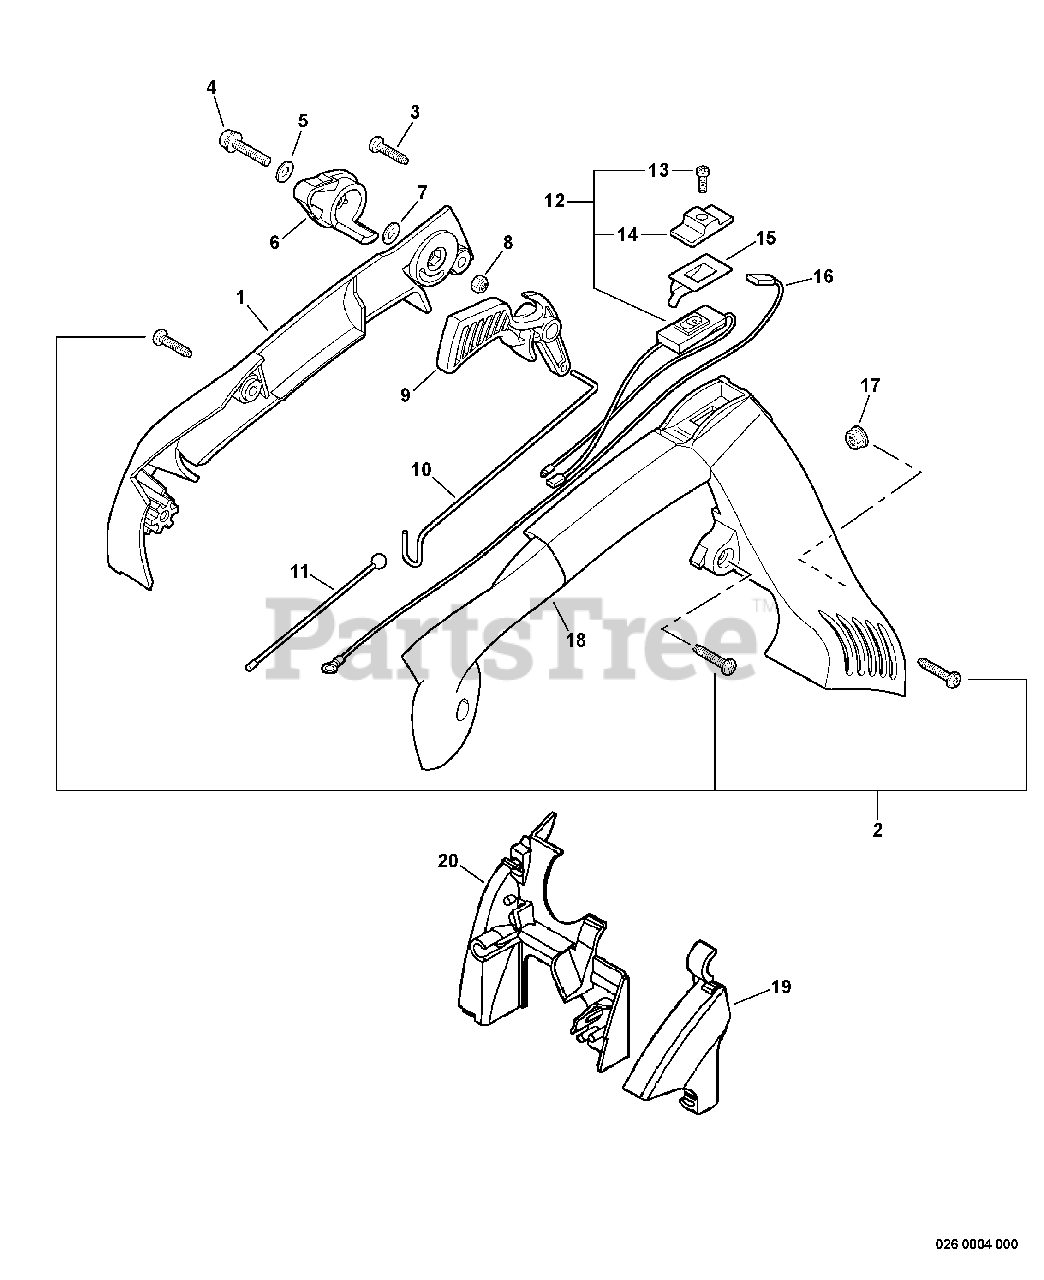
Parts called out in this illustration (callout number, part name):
1	COVER, HANDLE
2	SCREW, TAPPING 5×20
3	SCREW 5×25
4	SCREW 5×25
5	WASHER 5.5×12×0.8
6	LEVER, THROTTLE
7	WASHER 5.5×12×0.8
8	NUT, LOCK M5
9	TRIGGER, THROTTLE
10	ROD, THROTTLE
11	CABLE, THROTTLE
12	SWITCH, ON-OFF
13	SCREW 3×10
14	KNOB, SWITCH - ORANGE
15	TERMINAL - GROUND
16	LEAD - GROUND
17	NUT, FLANGE M5
18	HANDLE, UPPER
19	COVER, THROTTLE
20	COVER, CYLINDER - PLASTIC
